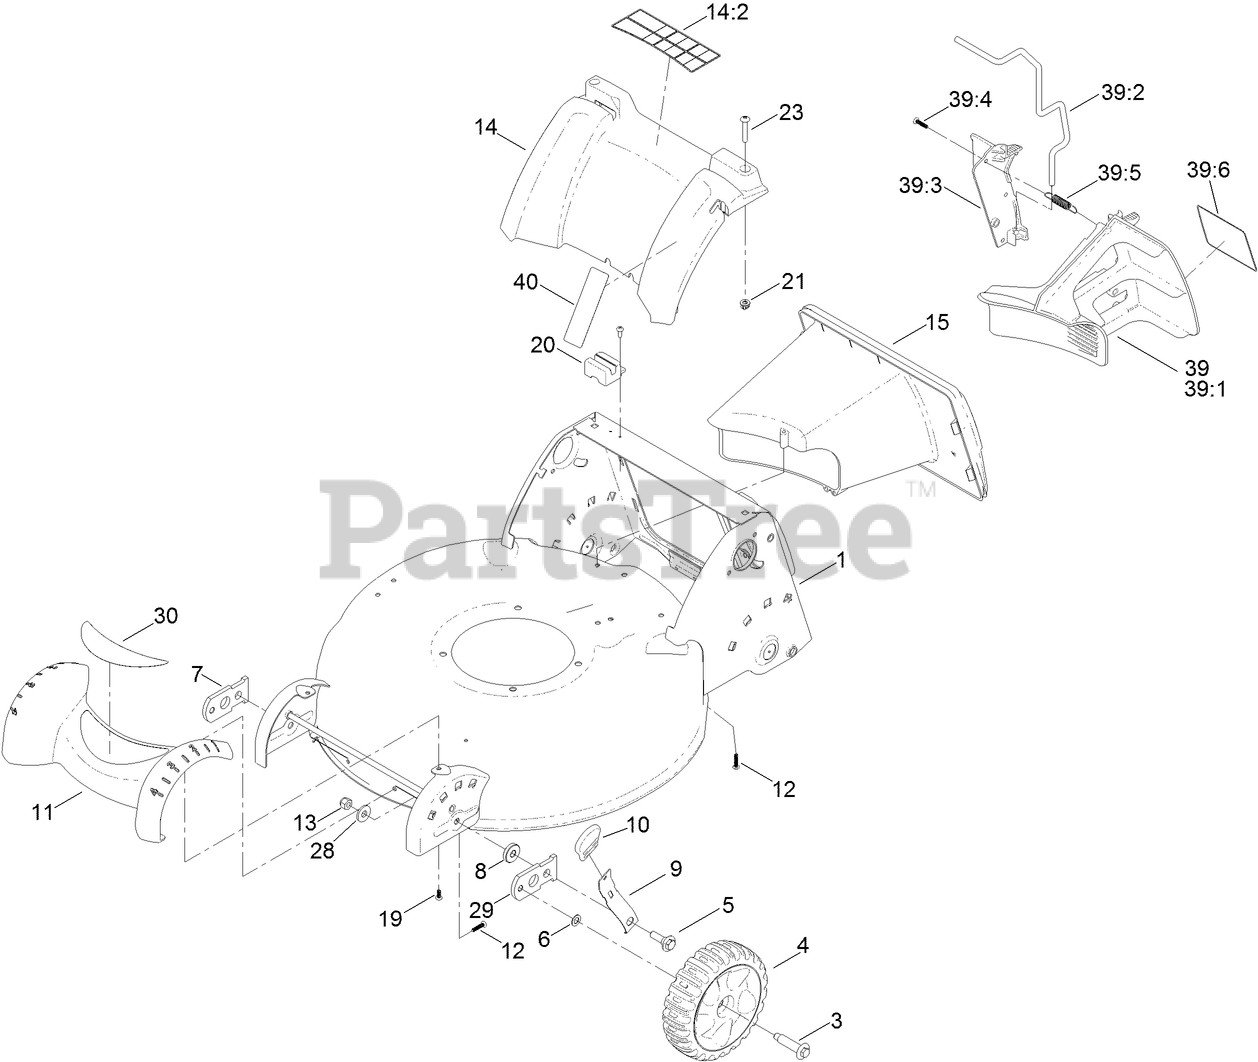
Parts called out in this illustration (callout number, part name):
1	DECK ASM
3	BOLT-SHOULDER
4	7 INCH WHEEL AND TIRE ASM
5	SCREW-SHOULDER, HWH
6	WASHER
7	ARM-PIVOT, RH
8	WASHER
9	ARM-SPRING
10	KNOB-HOC
11	COVER-FRONT
12	SCREW-PLASTITE
13	NUT-LOCK, NI
14	REAR COVER ASM
14:2	DECAL-WARNING
15	TUNNEL
19	SCREW-PLASTITE
20	MODULE-SWITCH
21	NUT-CLIP
23	SCREW-PTH
28	WASHER-HARDENED
29	ARM-PIVOT, LH
30	DECAL-FRONT (CE)
39	MULCH PLUG ASM
39:1	PLUG-MULCH, LH
39:2	LATCH-PLUG, MULCH
39:3	PLUG-MULCH, RH
39:4	SCREW-PLASTITE
39:5	SPRING-EXTENSION
39:6	DECAL-PLUG, MULCH
40	DECAL-STOW, QUICK
